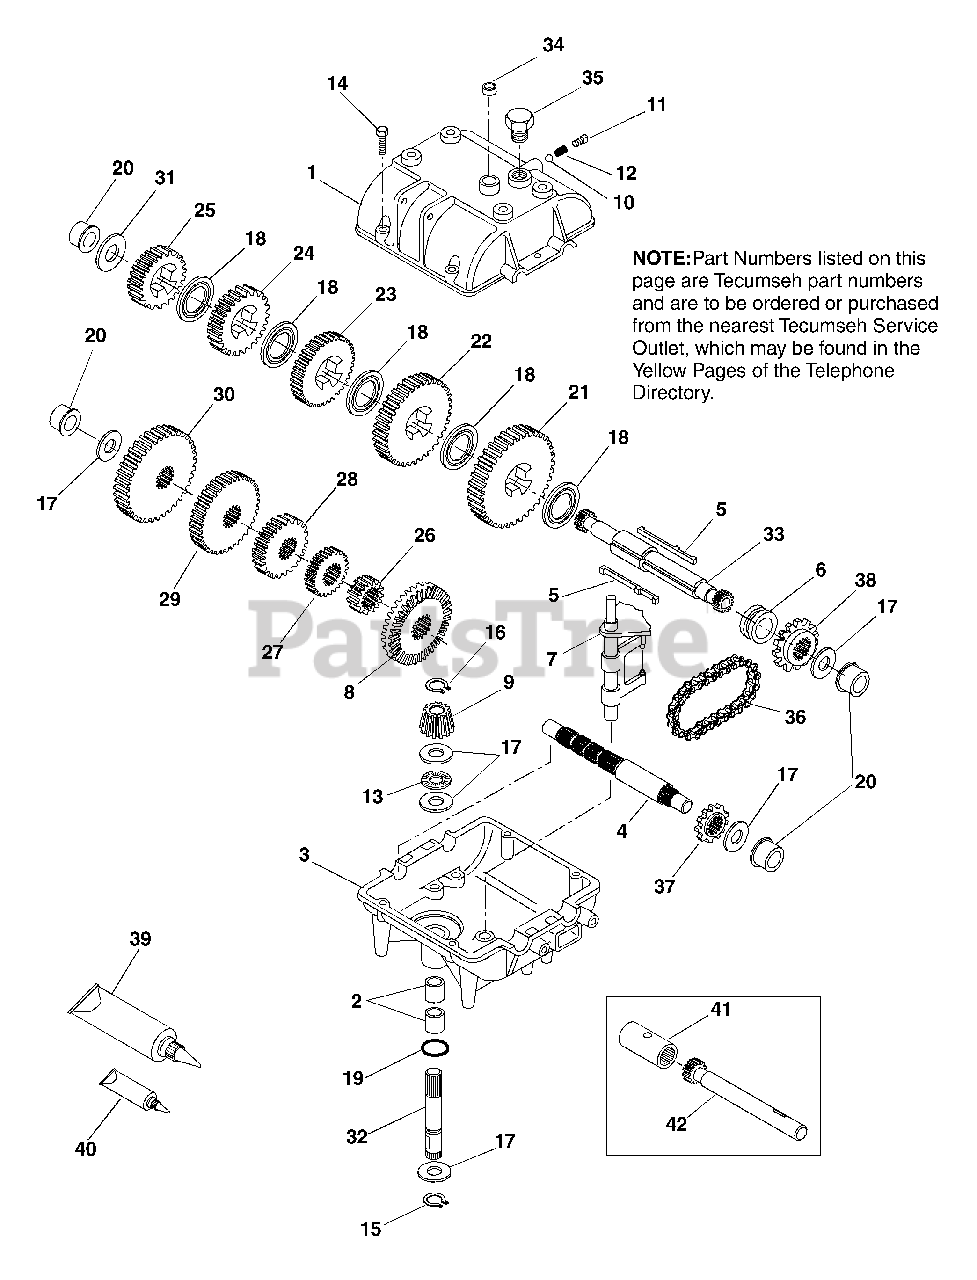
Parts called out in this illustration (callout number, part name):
1	Transmission Cover
2	Needle Bearing .625 ID x .50
2	Needle Bearing .625 ID x .75
3	Transmission Case
4	Countershaft
5	Shift Key
6	Shift Collar
7	Shift Rod & Fork Assembly
8	Bevel Gear (42 Teeth)
9	Bevel Pinion (14 Teeth-Steel)
10	Steel Ball .31 Diameter
11	Set Screw .38-16 x .38
13	Thrust Bearing
14	Screw .25-20 x 1.25
15	Ring, Retaining
16	Ring, Retaining
19	"O"-Ring
20	Bushing-Flanged
21	Spur Gear (37 Teeth)
22	Spur Gear (35 Teeth)
23	Spur Gear (32 Teeth-Steel)
24	Spur Gear (30 Teeth)
25	Spur Gear (27 Teeth)
26	Spur Gear (12 Teeth)
27	Spur Gear (15 Teeth)
28	Spur Gear (18 Teeth)
29	Spur Gear (20 Teeth)
30	Spur Gear (23 Teeth)
32	Input Shaft 3.69 long
33	Shifter and Brake Shaft
34	Square Cut Ring
35	Threaded Plug
36	Roller Chain (No. 41, 24 Links
37	Sprocket (9 Teeth)
38	Sprocket (18 Teeth)
39	Grease (32 oz. Bottle Bentonite Grease)
40	Gasket Eliminator (Loctite #515)
41	Coupling (1.813 OD)
41	Coupling (1.188 OD)
42	Connector (6.095 long)
42	Connector (6.25 long)
42	Connector (6.630 long)
42	Connector (7.000 long)
